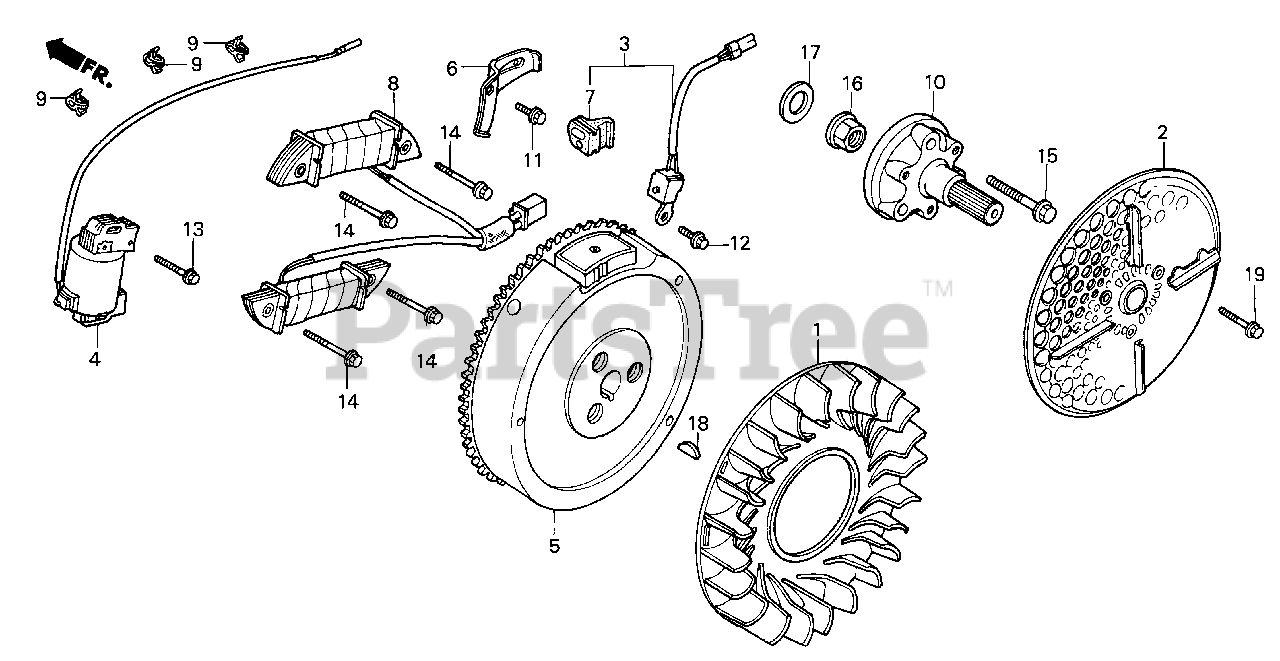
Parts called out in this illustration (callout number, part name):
1	FAN, COOLING
2	GRID, SCREEN
5	FLYWHEEL
6	CLAMP, WIRE
8	COIL ASSY., CHARGE
10	SHAFT, ENGINE P.T.O.
11	BOLT, FLANGE (6X12) (CT200)
14	BOLT, FLANGE (6X42)
15	BOLT, ENGINE P.T.O.
16	NUT, SPECIAL (16MM)
17	WASHER, FLYWHEEL
18	KEY, SPECIAL WOODRUFF (25X18)
19	BOLT, FLANGE (6X25)
